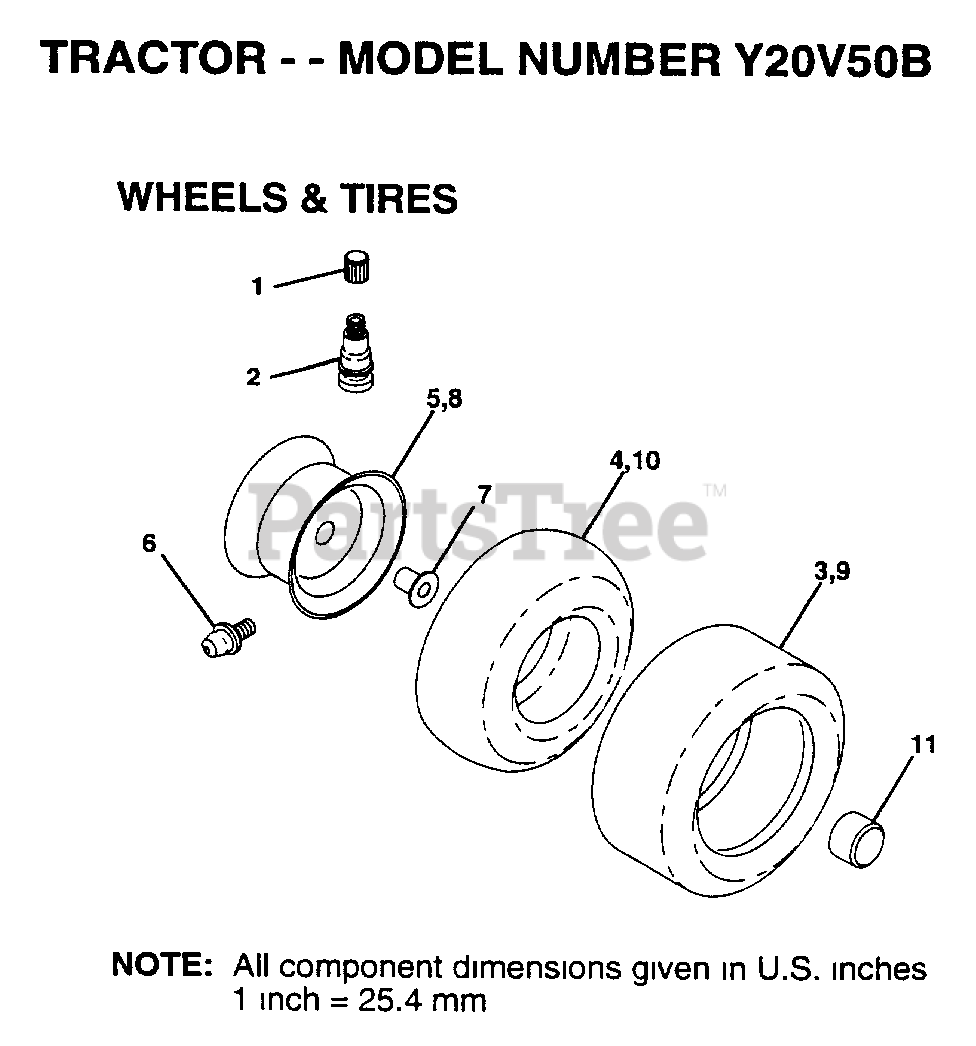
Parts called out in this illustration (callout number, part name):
1	VALVE CAP
2	VALVE STEM LT
4	TUBE.16X6.5/7.5-8
5	RIM.FRONT.
6	FITTING LT
7	"FLANGE, BEARING"
8	"WHEEL,REAR"
10	TUBE.23X8/10-12
11	HUB CAP
